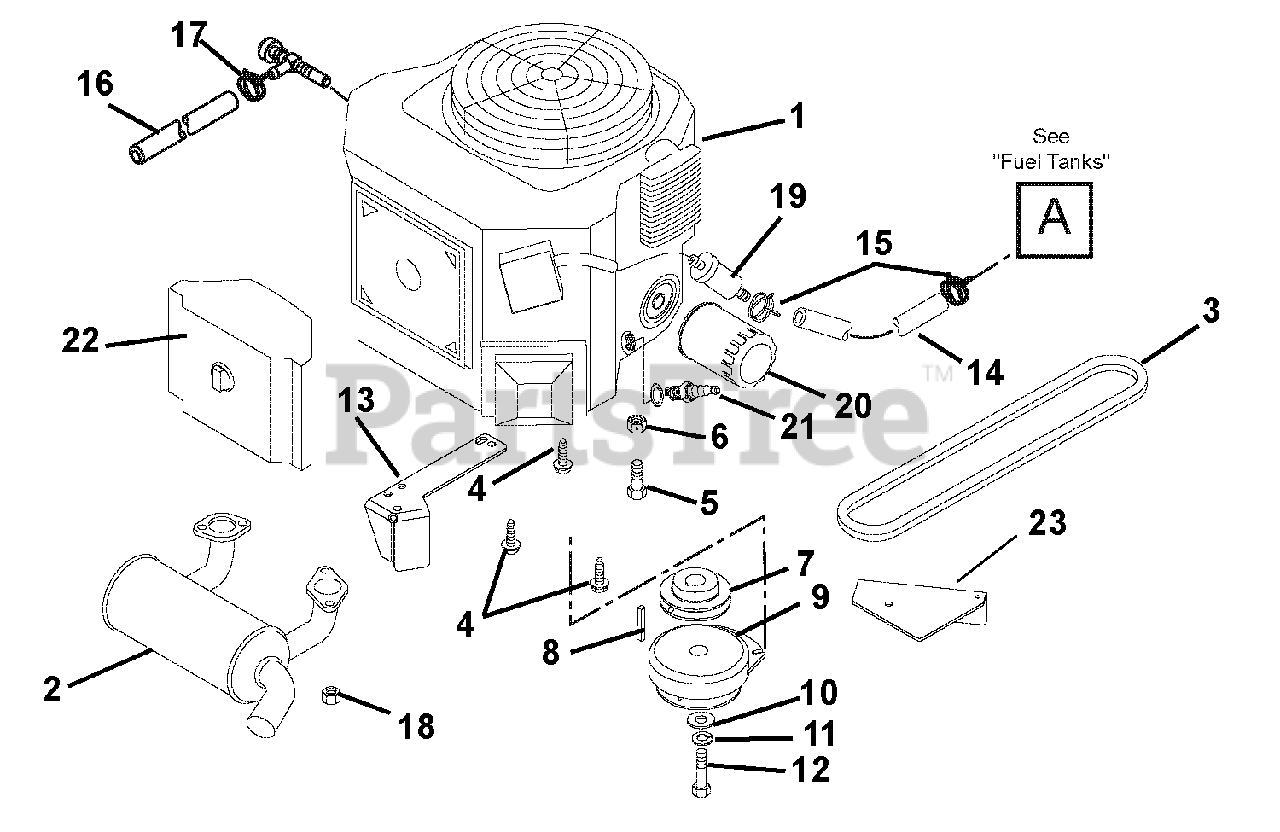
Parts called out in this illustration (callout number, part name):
1	ENGINE, 17HP KAW FH500V-AS43-R
2	MUFFLER, KAW. (COMPACT-Z)
3	V-BELT, HA-RAW EDGE
4	BLT, TAP .38-16X1.5 PH TRX YZ
5	@BLT-HEX .31-18X1.50 GR5 YWZC
6	@NUT-LK-NYL-FLG .31-18 YWZC
7	PLY-V 4.OO X 1.00
8	KEY-SQ .25X.625X.25 SAE 8630
9	CLUTCH,ELECTRIC PTO
10	WSHR-FL-STL .469X2.00X.25 YWZC
11	@WSHR-LK .44X.109 REG YWZC
12	BLT-HEX .44-20X2.50 GR5 YWZC
13	WMT, CLUTCH STOP
14	HOSE, 5.75"-1/4" ID GAS LINE
15	CLAMP-HOSE WIRE .490/.510X.116
16	HOSE, 1/2 X 6.00
17	CLAMP,.88 DIA. HOSE
18	NUT-LK-TOP M8-1.25 YWZC
19	FUEL FILTER - KAWASAKI
20	FILTER,OIL - KAW
21	PLUG, SPARK
22	AIR FLTR,PAPER
22	FILTER, FOAM AIR PRE-
23	GUARD - CLUTCH WIRE - CZ/XL
